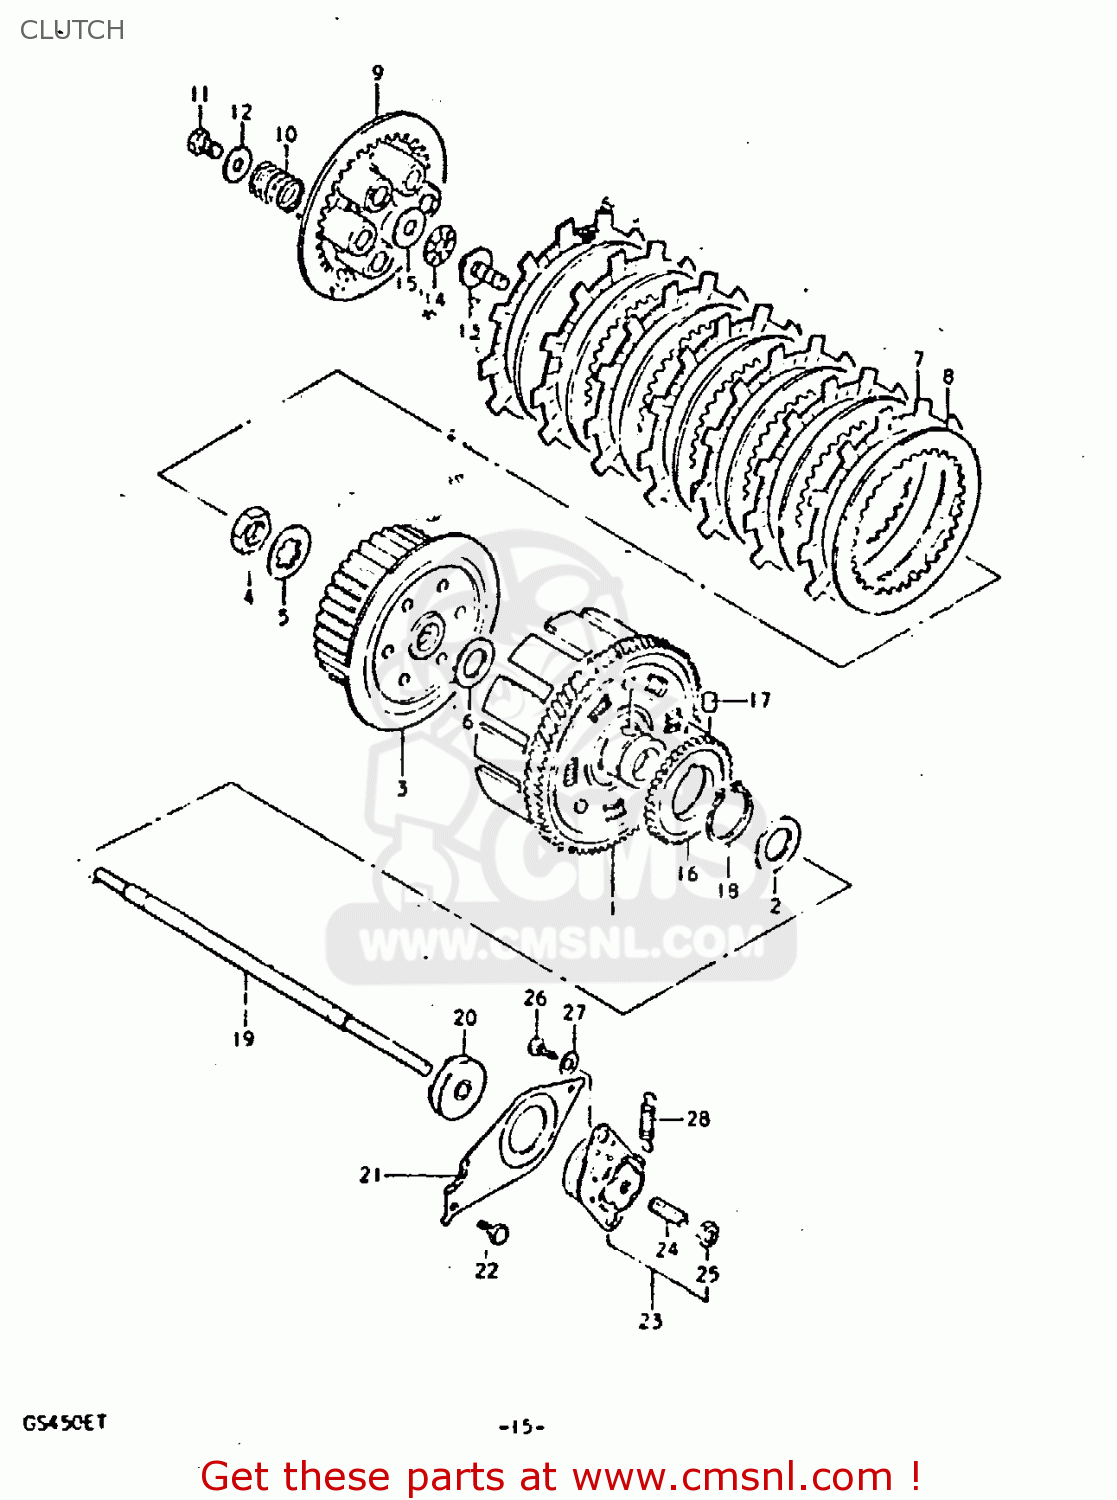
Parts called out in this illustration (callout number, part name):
1	GEAR ASSEMBLY,PRIMARY DRIVE
2	WASHER
3	HUB,CLUTCH SLEEVE
4	NUT (20MM)
5	WASHER,LOCK
6	WASHER(20X44X3)
7	PLATE,CLUTCH DRIVE (MCA)
8	PLATE,CLUTCH DRIVEN (NAS)
9	DISC,CLUTCH PRESSURE
10	SPRING
11	BOLT, UPPER
12	WASHER
13	PIECE,CLUTCH PUSH
14	BEARING(15X28X2)
15	WASHER
16	GEAR,OIL PUMP DRIVE
17	PIN(6X6)
18	CIRCLIP
19	ROD,CLUTCH PUSH
20	SEAL,OIL(6X34X10)
21	PLATE,CLUTCH PUSH ROD
22	BOLT
23	SCREW ASSEMBLY,CLUTCH RELEASE
24	SCREW
25	NUT 6MM
26	SCREW
27	WASHER
28	SPRING
